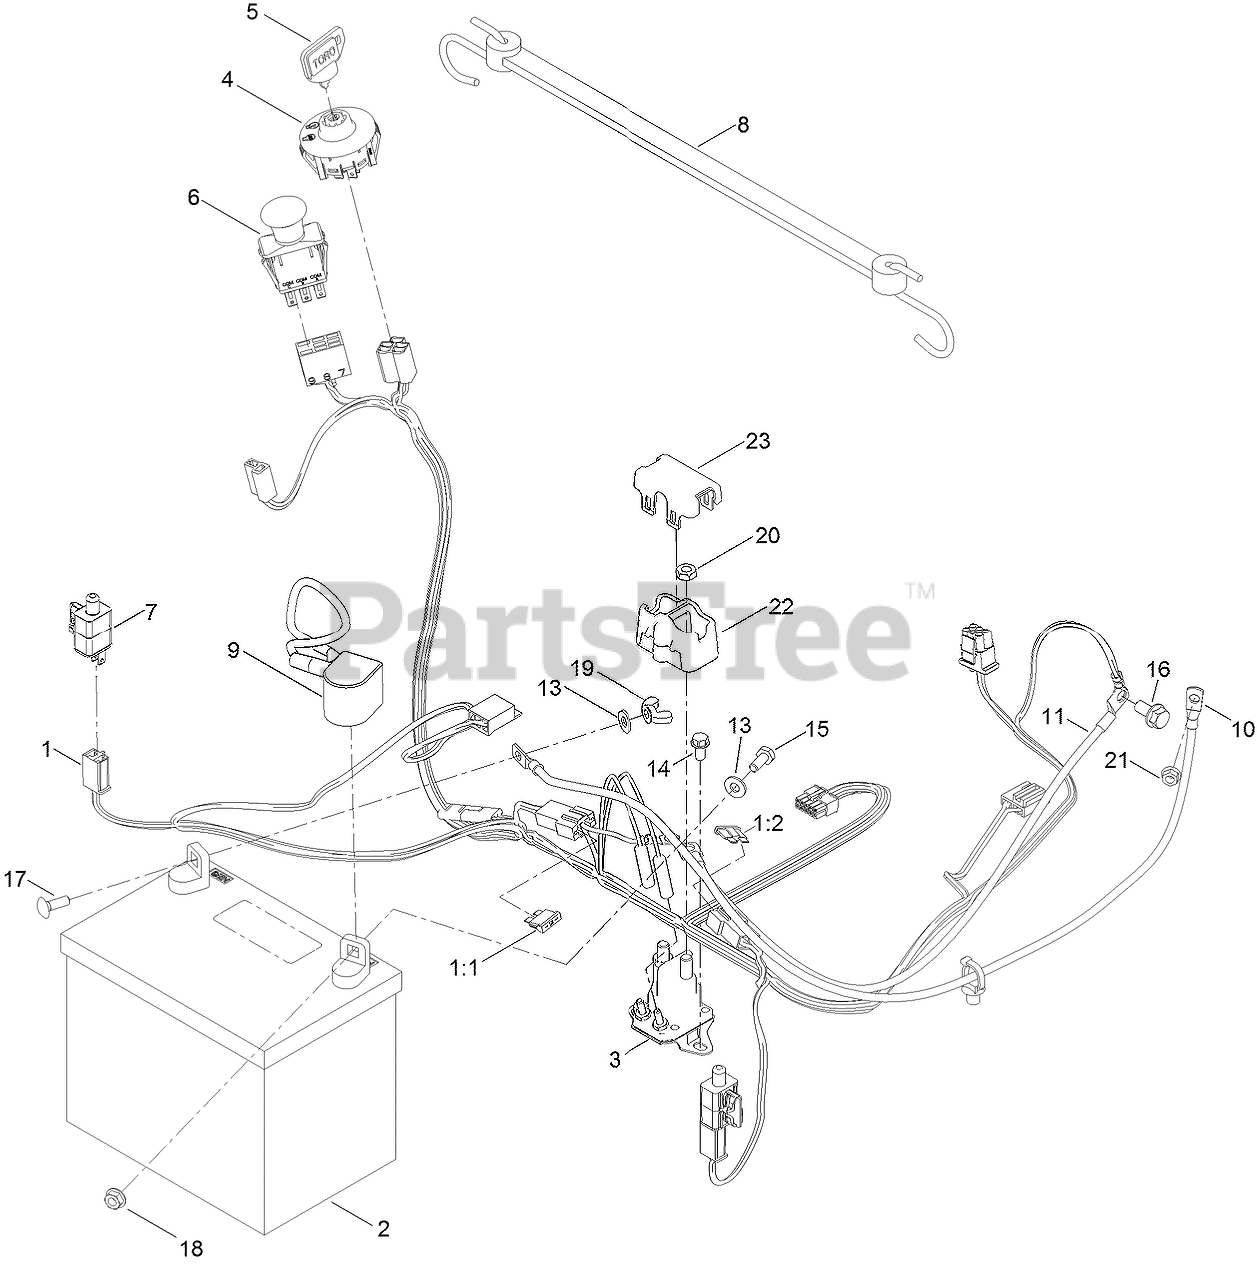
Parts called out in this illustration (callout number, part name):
1	HARNESS-WIRE
1:1	FUSE-BLADE, 15 AMP
1:2	FUSE-BLADE, 25 AMP
2	BATTERY
3	SOLENOID
4	SWITCH-IGNITION
5	KEY-IGNITION
6	SWITCH-PTO
7	SWITCH
8	STRAP-RUBBER
9	CABLE-BATTERY, POS
10	CABLE-BATTERY, RED (8 GAUGE)
11	CABLE-BATTERY, BLACK
13	WASHER-FLAT
14	SCREW-HWH
15	SCREW-HH
16	SCREW-HHF
17	BOLT-CARR
18	NUT-HF
19	NUT-WING
20	NUT-HJ
21	NUT-HF
22	COVER-SOLENOID
23	CAP-SOLENOID
